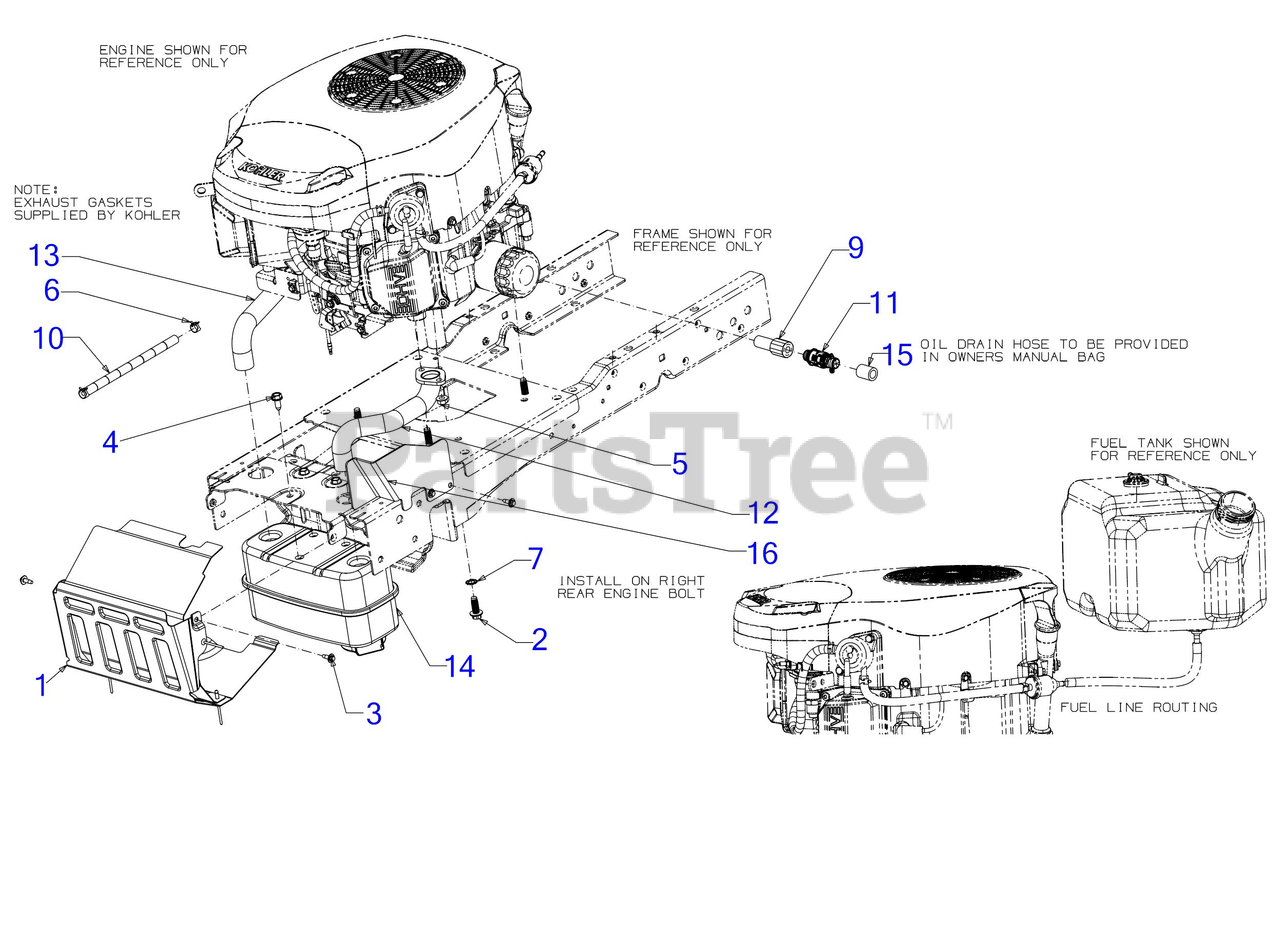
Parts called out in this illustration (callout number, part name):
1	MUFFLER SHIELD ASSEMBLY
2	SCREW 3/8-16 x 1
3	SCREW M6-1 x .625
4	SCREW M8-1.25 x .750
5	HEX FLANGE NUT M8X
6	HOSE CLAMP 1/20
7	LOCK WASHER 3/8
9	OIL DRAIN FITTING 3/8-18 NPT (KH TWIN)
10	FUEL HOSE LOW PERMEATION
11	OIL DRAIN VALVE
12	EXHAUST PIPE (LH) (KOHLER)
13	EXHAUST PIPE (RH) (KOHLER)
14	EXHAUST MUFFLER (TWIN)
15	DRAIN HOSE 14''
